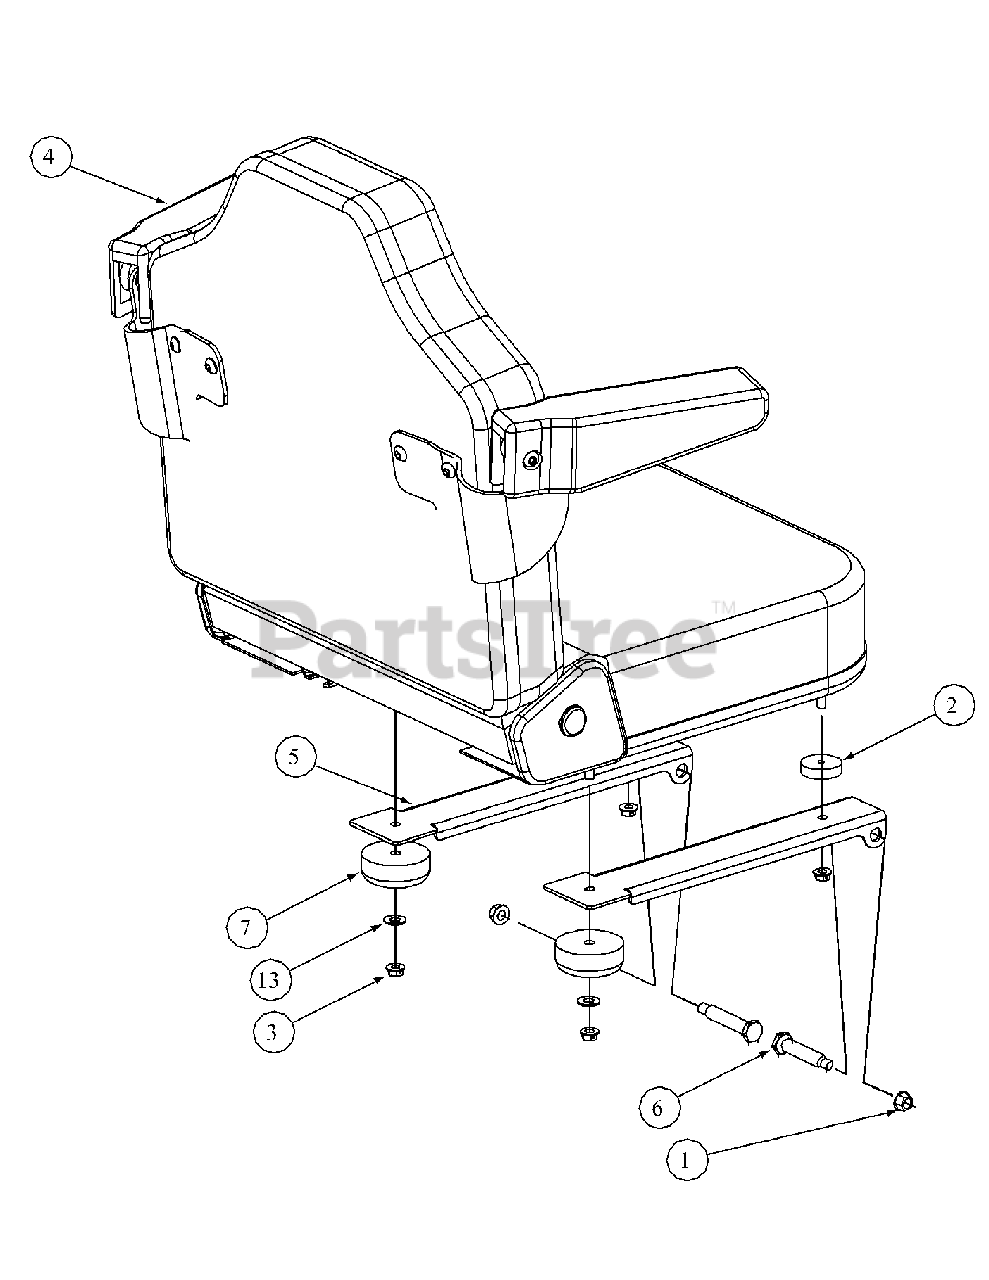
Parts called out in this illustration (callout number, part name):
1	Nut, Hex 3/8-16 Flange Lock
2	Spacer, 0.345 ID x 1.50 OD x .41
3	Lock Nut, Hex Flange, 5/16-18
4	Adjustable Seat, Black embossed,
5	Mounting Bracket, Seat
6	Shoulder Screw, .50x2.345, 3/8-16
7	Grommet, 2.5 OD x 1.0 Long
13	Washer
